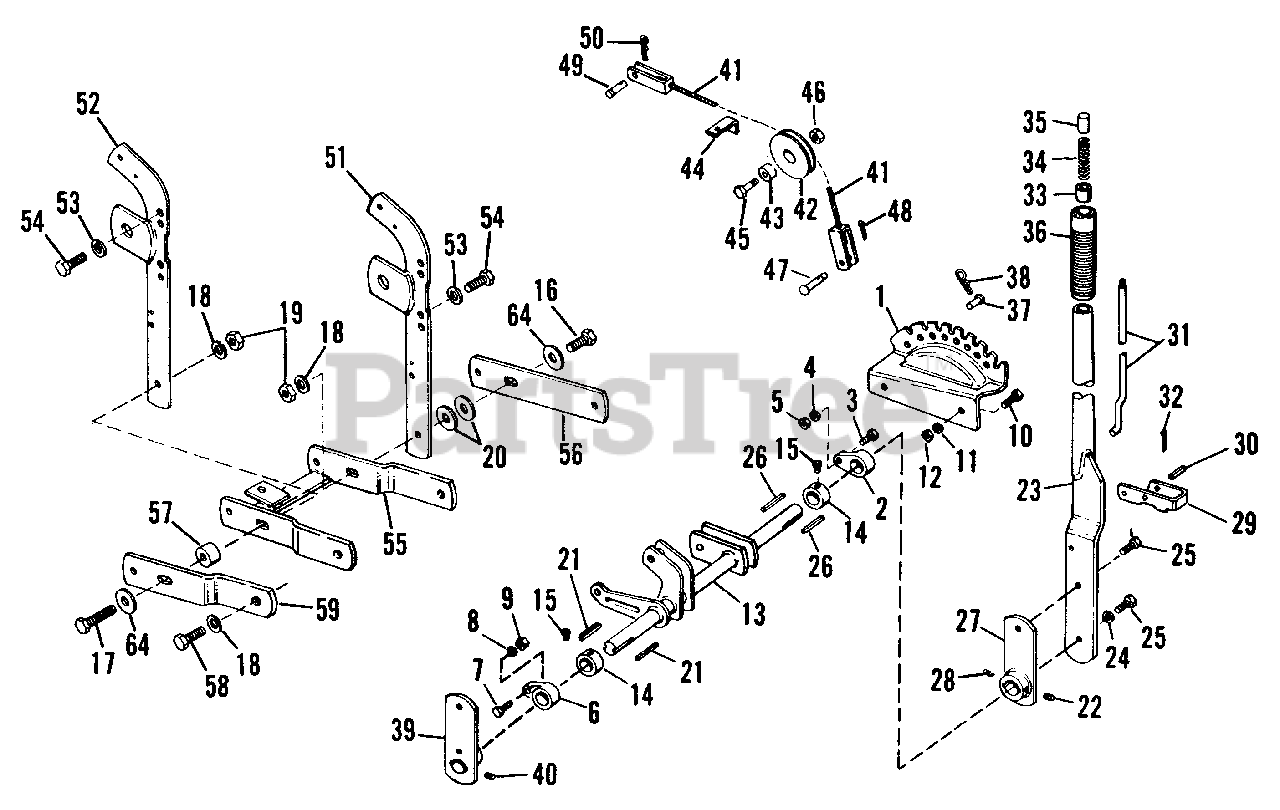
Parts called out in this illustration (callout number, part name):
1	Lift Lever Quadrant
2	Lift Lever Bearing
3	Hex Capscrew, 5/16"-18 x 1-1/4"
4	Lockwasher, 5/16"
5	Full Hex Nut, 5/16"-18
6	Lift Lever Bearing
7	Hex Capscrew, 5/16"-18 x 1-1/4"
8	Lockwasher, 5/16"
9	Hex Nut, 5/16"-18
10	Hex Capscrew, 3/8"-16 x 3/4"
11	Lockwasher, 3/8"
12	Full Hex Nut, 3/8"
13	Lift Shaft Assembly
14	Set Collar
15	Set Screw Sq. Hd., 5/16"-18 x 3/8"
16	Hex Capscrew, 7/16"-14 x 1-1/2"
17	Hex Capscrew, 7/16"-14 x 1-3/4"
18	Lockwasher, 7/16"
19	Full Hex Nut, 7/16"-14
20	Plain Washer, 5/16"
22	Set Screw, 5/16"-18 x 1/4"
23	Lift Lever Assembly
24	Lockwasher, 3/8"
25	Hex Capscrew, 3/8"-16 x 1"
27	Lift Lever Assy. Inner Section
28	Set Screw, 5/16"-18 x 1/4"
29	Lift Lever Latch
30	Roll Pin, 3/8" x 1-1/4"
31	Latch Rod
32	Cotter Pin, 3/32" x 3/4"
35	Thumb Button
36	Handle Grip
38	Spring Clip
39	Front Lift Lever Assembly
40	Set Screw, 5/16"-18 x 1/4"
41	Cable Assembly, Lift
44	Cable Guard
46	Hex Jam Lock Nut, 3/8"-16
47	Pin
48	Cotter Pin, 3/32" x 7/8"
50	Spring Clip
51	Arm Assembly
52	Arm Assembly
53	Lockwasher, 7/16"
54	Hex Capscrew, 7/16"-14 x 1"
55	Draw Bar Assembly
58	Hex Capscrew, 7/16"-14 x 2-1/4"
